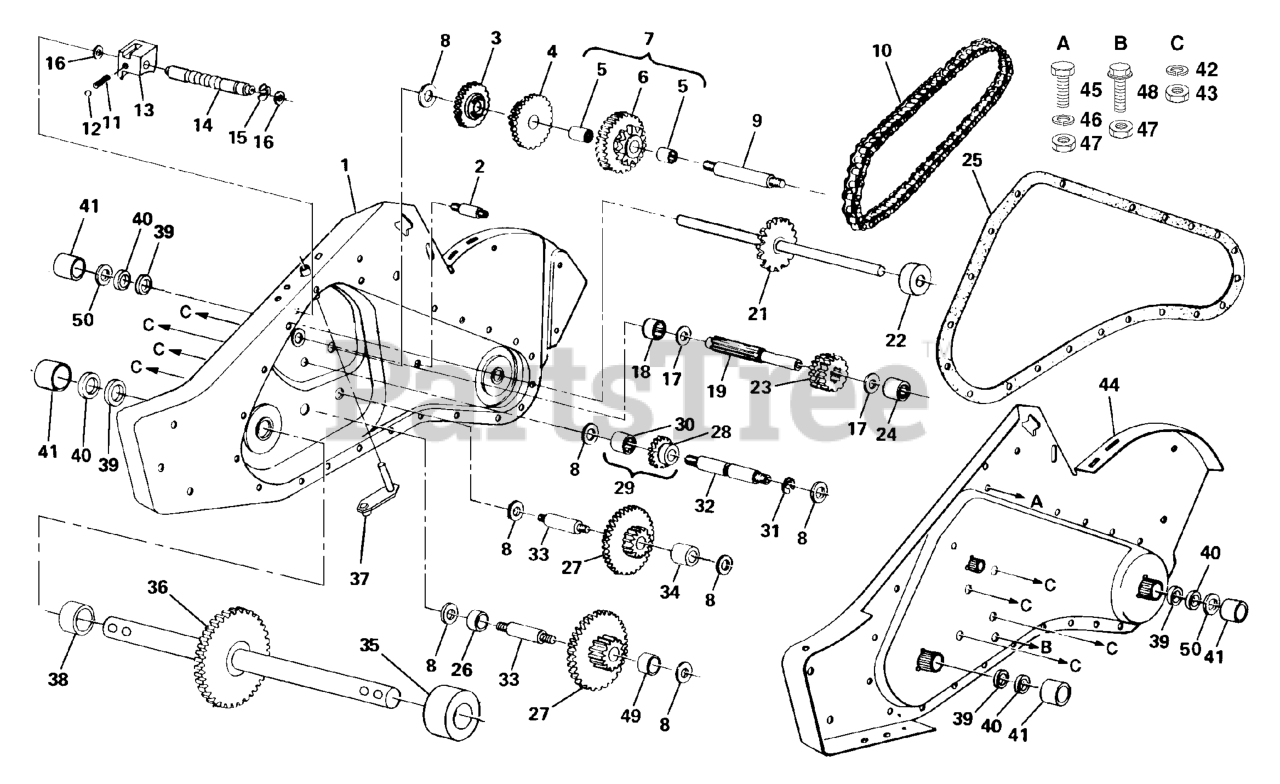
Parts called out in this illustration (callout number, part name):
1	GEARCASE ASMBLY RH
3	GEAR, REVERSE
4	GEAR, CLUSTER (2 GEAR SET)
5	BEARING.NEEDLE.CRT
6	SPROCKET ASMBLY, TINE
7	SPROCKET ASMBLY W/BEARINGS
9	SHAFT.REDUCTION.TILLER
10	CHAIN.ROLLER.TILLER
11	SPRING-SHIFT CRT
12	STEEL BALL KIT
13	SHIFT FORK TI
14	SHAFT, SHIFT
16	WASHER SEAL
17	THRUST WASHER
18	BEARING TI
19	SHAFT, INPUT
21	SHAFT TINE CRT
22	SPACER 1.008X1-3/4X.645
23	PINION, INPUT
24	NEEDLE BRNG LT
25	GASKET, GEARCASE
27	GEAR, CLUSTER CRT
28	REVERSE GEAR
29	GEAR ASMBLY, REVERSE IDLER
30	NEEDLE BEARING TI
32	SHAFT, REVERSE IDLER
33	SHAFT, REDUCTION
34	SPACER.765 X 1.12 X .380.
35	SPACER, GROUND DRIVE RH
36	SHAFT ASSY CRT
37	BRACKET ASM.SHIFT.CRT
38	SPACER, GROUND DRIVE
39	OIL SEAL STD
41	CUP
42	LOCKWASHER
43	NUT.ASF.HEX.7/16
44	GEARCASE LH
45	BOLT.FIN.HEX.5/16-18X3/4
46	WASHER.LOCK.HVY.HLCL.SPR.5/16
47	NUT
48	SCREW 5/16-18X4
50	RING.SPIRAL.CRT.TILLER
